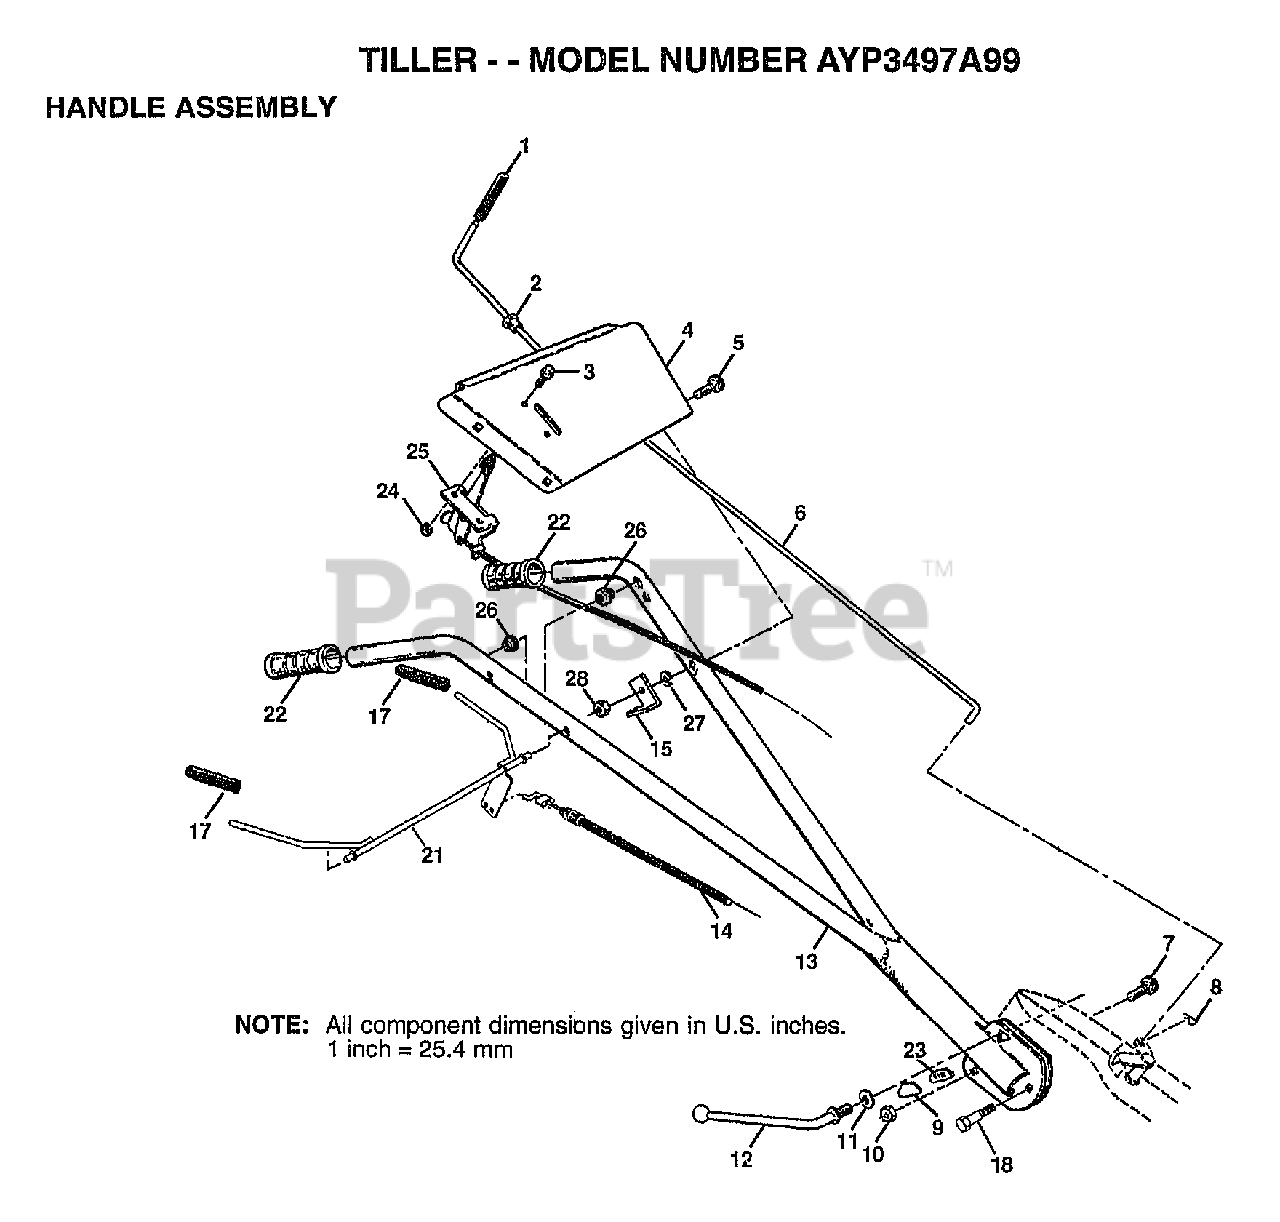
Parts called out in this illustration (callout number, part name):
1	GRIP TI
2	BUSHING
3	SCREW.PNHD.10-24
5	BOLT CARRIAGE CRT
6	ROD SHIFT CRT
7	BOLT D
8	RETAINER M
9	LOCK CRT
10	LOCKNUT
11	WASHER CRT
12	LEVER LOCK CRT
14	CABLE.CLUTCH.Z-BE
15	BRACKET.CLUTCH.CA
17	GRIP BAR CRT
18	BOLT PIVOT
21	BAR CONTROL
22	"GRIP,HANDLE"
23	LOCK.HANDLE
25	CONTROL.THROTTLE
26	GROMMET.HANDLE.V-
27	LOCKWASHER
28	NUT
